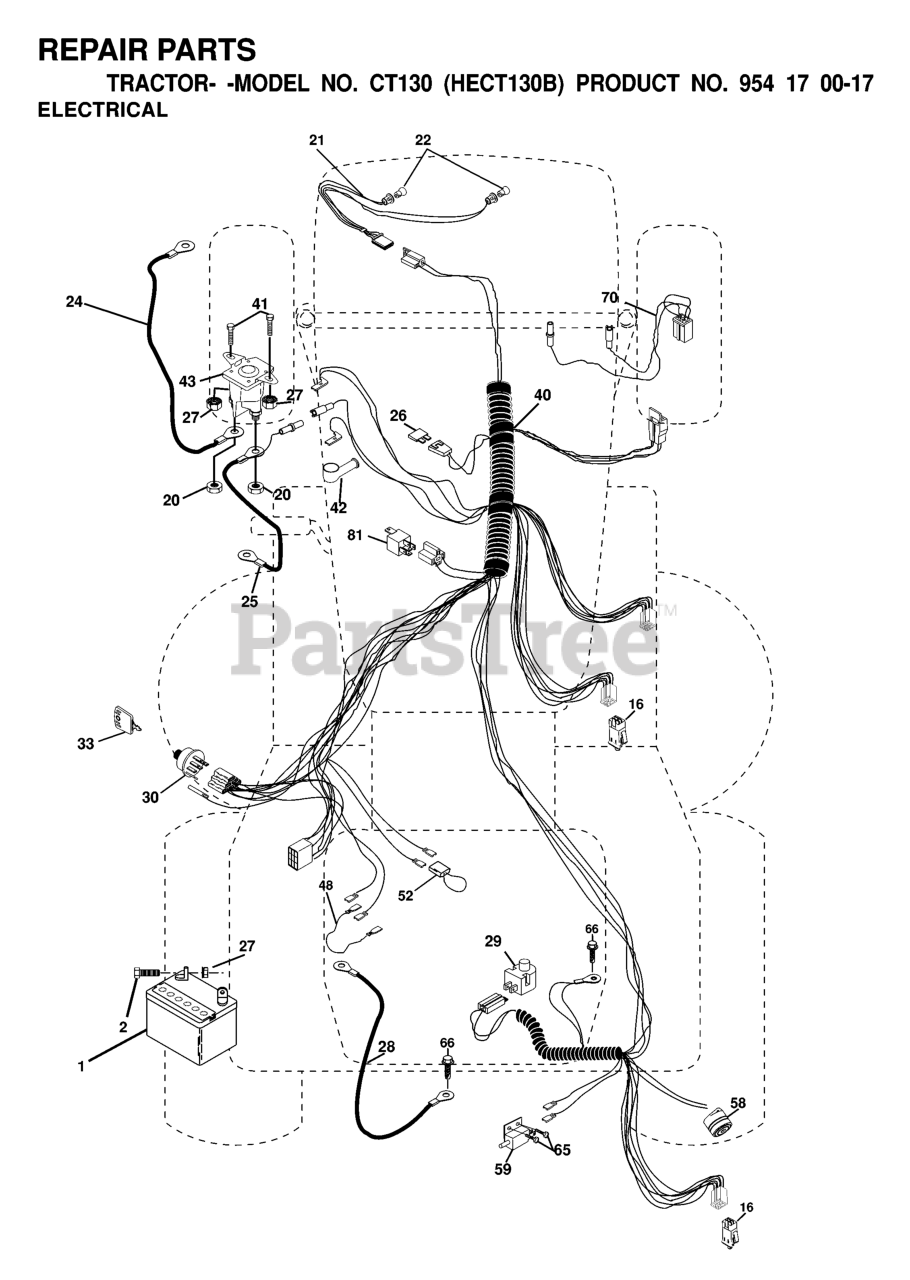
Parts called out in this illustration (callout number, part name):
1	BATTERY 12 VOLT 25 AMP
2	BOLT.HEX.1/4.X.3/4.DICHROMATE
16	SWITCH INTERLOCK
20	NUT
24	BATTERY CABLE GT
25	CABLE BATTERY
26	FUSE 15 AMP
27	NUT
28	CABLE GROUND
29	PLUNGER SWITCH (COLOR:OLIVE)
30	SWITCH IGN
33	KEY MLD GEN DELTA
40	Harness Ign Crd Noram
41	BOLT
42	TERMINAL COVER
43	SOLINOID
48	ADAPTER.AMMETER
52	WIRE PROTECTION LOOP
58	BUZZER
65	Screw, Hex Wsh. Tap #10-16 x 1/2
70	Harness Engine B&S
81	RELAY.ASSY.T
